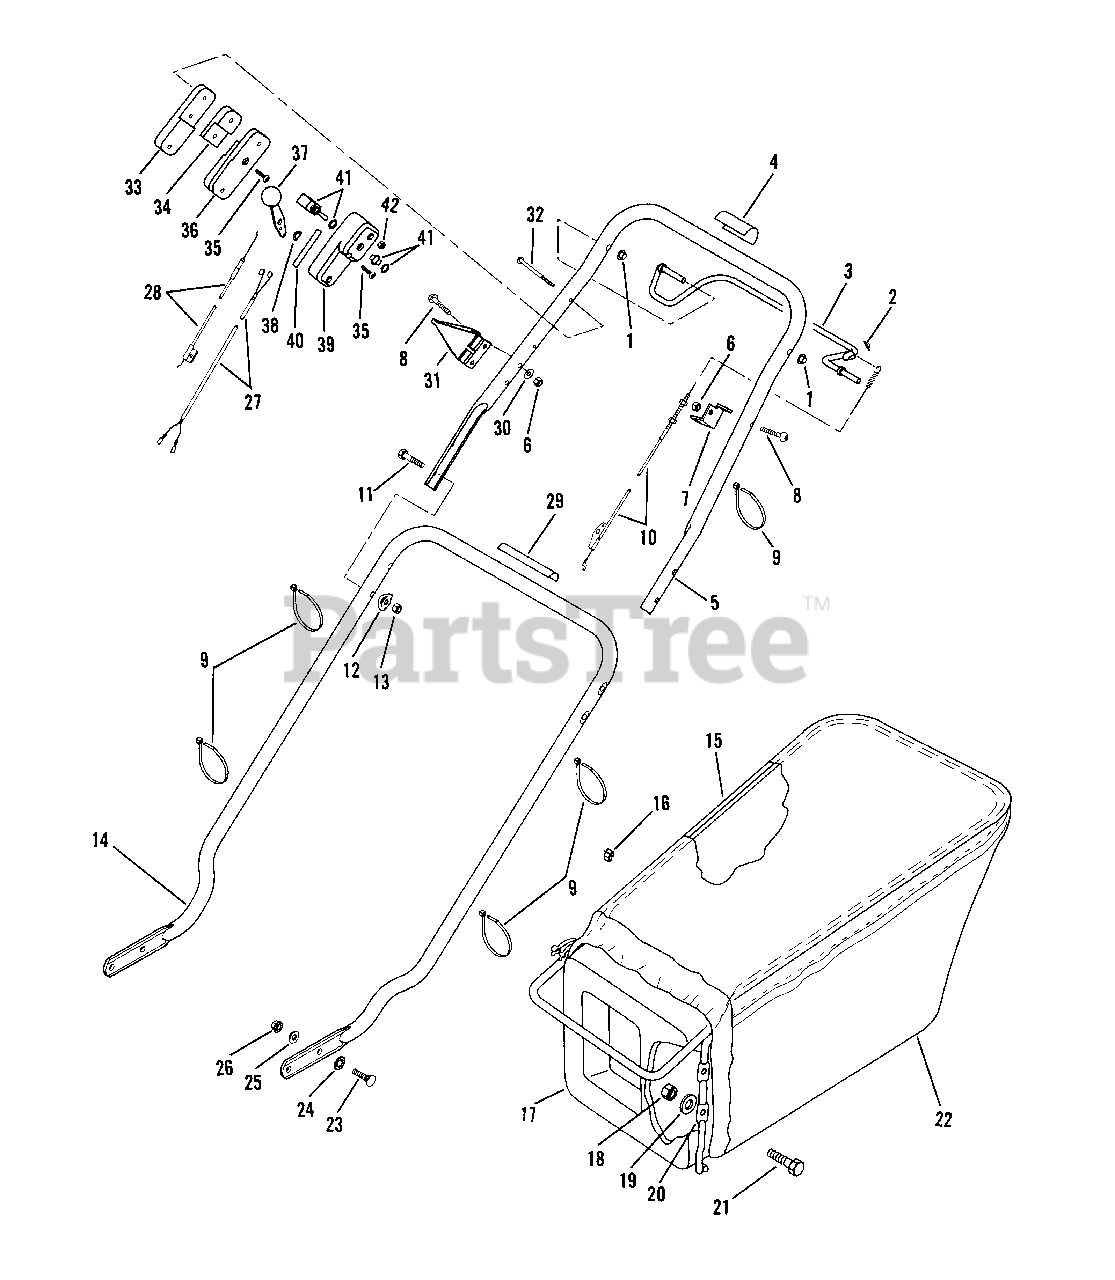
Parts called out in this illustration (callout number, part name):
1	Palnut
2	Nut-Push On
3	Control Lever-Bail
4	Decal-Traction Drive
5	Handle Section-Top
6	Nut
7	Conduit Anchor
8	Screw
9	Tie Strap
10	Control Cable Assembly
11	Screw
12	Washer-Curved
13	Nut
14	Handle Section-Lower
15	Hanger Bag
16	"S" Clip
17	Bag Adapter
18	Nut-Bag Adapter
19	Washer-Bag Adapter
20	Latch Bar Assembly
21	Screw-Bag Adapter
22	Grass Bag Assembly
23	Bolt-Handle to Handle Bracket
24	Lockwasher
25	Washer
26	Nut-Flanged
27	Wire Harness Assembly
28	Throttle Cable
29	Decal-Special Training
30	Washer
31	Rope Guide Assembly
32	Screw
33	Control Case
34	Escutcheon Plate
35	Screw
36	Throttle Case-Center
37	Lever and Knob Assembly
38	Washer
39	Throttle Case-Inner
40	Decal-Throttle Control
41	Switch Assembly
42	Nut
